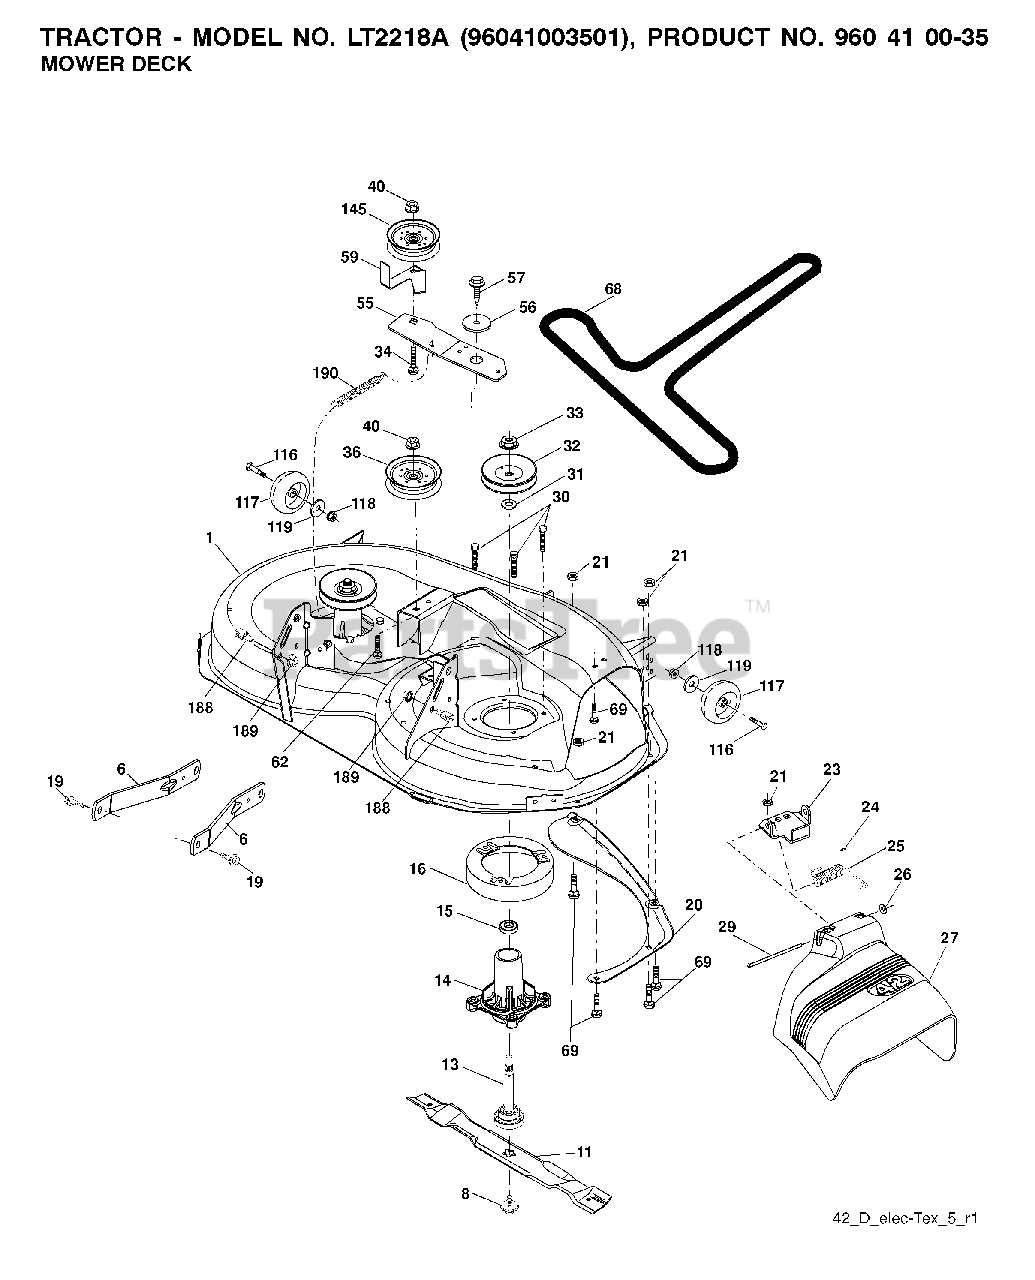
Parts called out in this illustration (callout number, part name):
1	DECK.WELDMENT.42"
6	ARM.SUSPENSION.MOWER.R
8	BOLT.WASHER.ASM.7/16-2
11	42" HI-LIFT BLADE
13	SHAFT.ASM.MDRL.N/GREASE.38
14	HOUSING MANDREL
16	STRIPPER, MWR ROUND
19	BOLT.SHOULDER
20	BAFFLE.VORTEX
21	LOCKNUT
23	BRKT.DEFLECTOR.38"2005+
24	CAP-SLEEVE LT
25	SPRING.TORSION.DEFLECT
26	NUT PUSH M
27	SHIELD.DEFLECTOR.MOWER.42"BLAC
29	ROD.HINGE
30	SCREW, WASHER HEAD
31	WASHER.SPACER.MANDREL
32	PULLEY/MANDREL
33	NUT.FLANGE.LOCK.TOP
34	BOLT.3/8-16X1.50
36	PULLEY.IDLER.2006
40	NUT LOCK FLG 3/8-16 UNC
55	IDLER.ARM
56	SPACER.RETAINER
57	SCREW 3/8-16X1
59	GUARD, BELT
62	BOLT
68	BELT V SECONDARY
69	BOLT
117	WHEEL.GAGE.HALF.SPOKED
118	LOCKNUT
119	WASHER
145	PULLEY.IDLER.48"PRIMARY
188	STUD.FASTNER.W/ANTI-ROTATE
189	NUT LOCK HEX FLANGE 5/16-18
190	SPRING.MOWER.DRIVE.ELECTRIC
